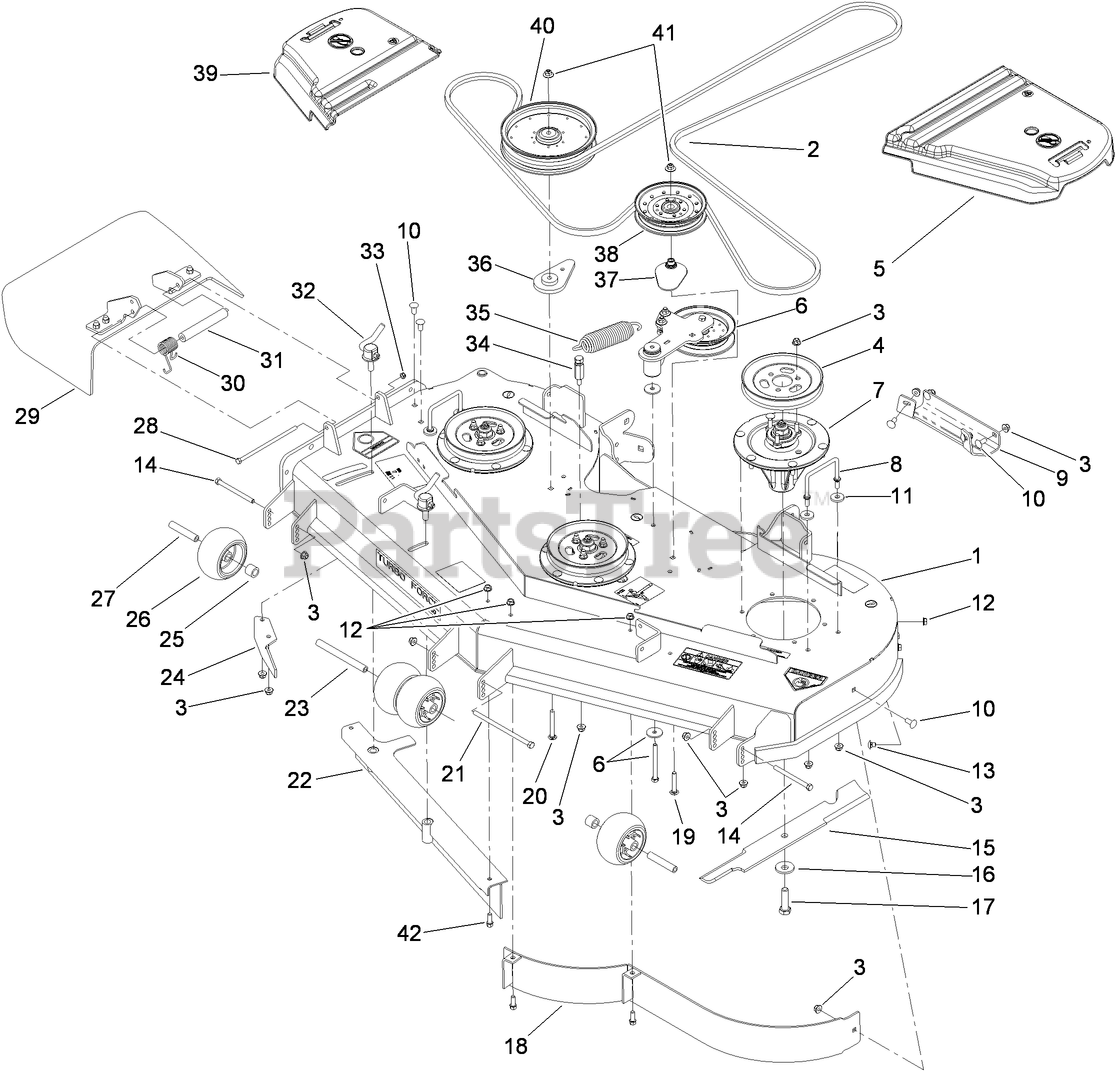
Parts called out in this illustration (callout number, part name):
1	DECK DECAL ASM
2	BELT-V
3	NUT-HF, NI
4	Pulley
5	COVER-BELT, LH
6	IDLER ARM ASM
7	SPINDLE ASM
8	WIREFORM-COVER
9	Plate-Skid
10	SCREW-CARR
11	WASHER
12	NUT-HHF, WHIZ
13	SCREW-CARR
14	SCREW-HH
15	BLADE-HI FLOW
16	Washer-Blade Bolt, Heavy
17	SCREW-BLADE
19	BOLT-CARR, SHORT NECK
20	SCREW-CARR
21	SCREW-HH
23	SPACER-WHEEL
24	BAFFLE-DISCHARGE
25	TUBE-SPACER
26	ROLLER-SCALP, ANTI
27	TUBE-SPANNER
28	SCREW-HH
29	RUBBER DEFLECTOR ASM
30	SPRING-TORSION
31	SPACER
32	LEVER ASM
33	NUT-LOCK, NI
34	ANCHOR-SPRING, TALL
35	EXTENSION-SPRING
36	SPACER-IDLER
37	SPACER-PULLEY
38	PULLEY-IDLER, FLAT
39	COVER-BELT, RH
40	PULLEY-IDLER
41	NUT-FLANGE, NI
42	SCREW-HWH
